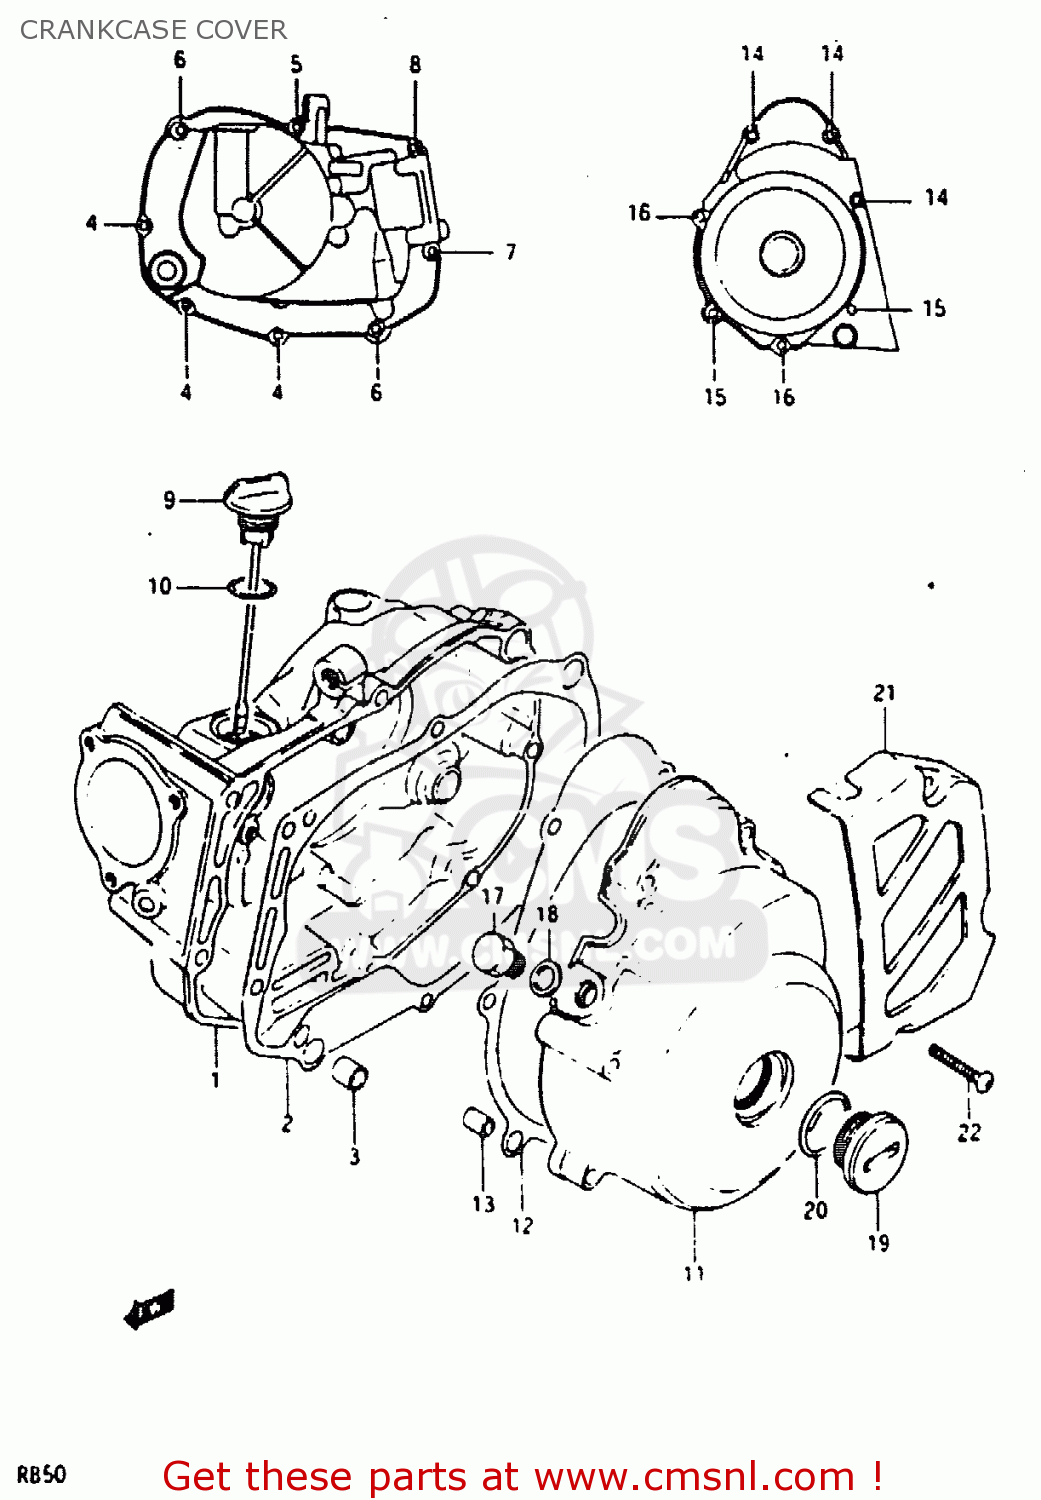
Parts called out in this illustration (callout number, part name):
1	COVER COMP,CLUTCH
2	GASKET,CLUTCH COVER (NAS)
3	PIN
4	SCREW
5	SCREW
6	SCREW
7	SCREW
8	SCREW
9	OIL LEVEL GAUGE
10	O RING(D:3.1,ID:16.8)
11	COVER
12	GASKET,MAGNETO COVER
13	PIN
14	SCREW
15	SCREW
16	SCREW
17	PLUG
18	GASKET(12.1X16.2X3.7) (NAS)
19	PLUG
20	O RING(D:3.1,ID:22.7)
21	COVER COMP,ENGINE SPROCKET
22	SCREW
